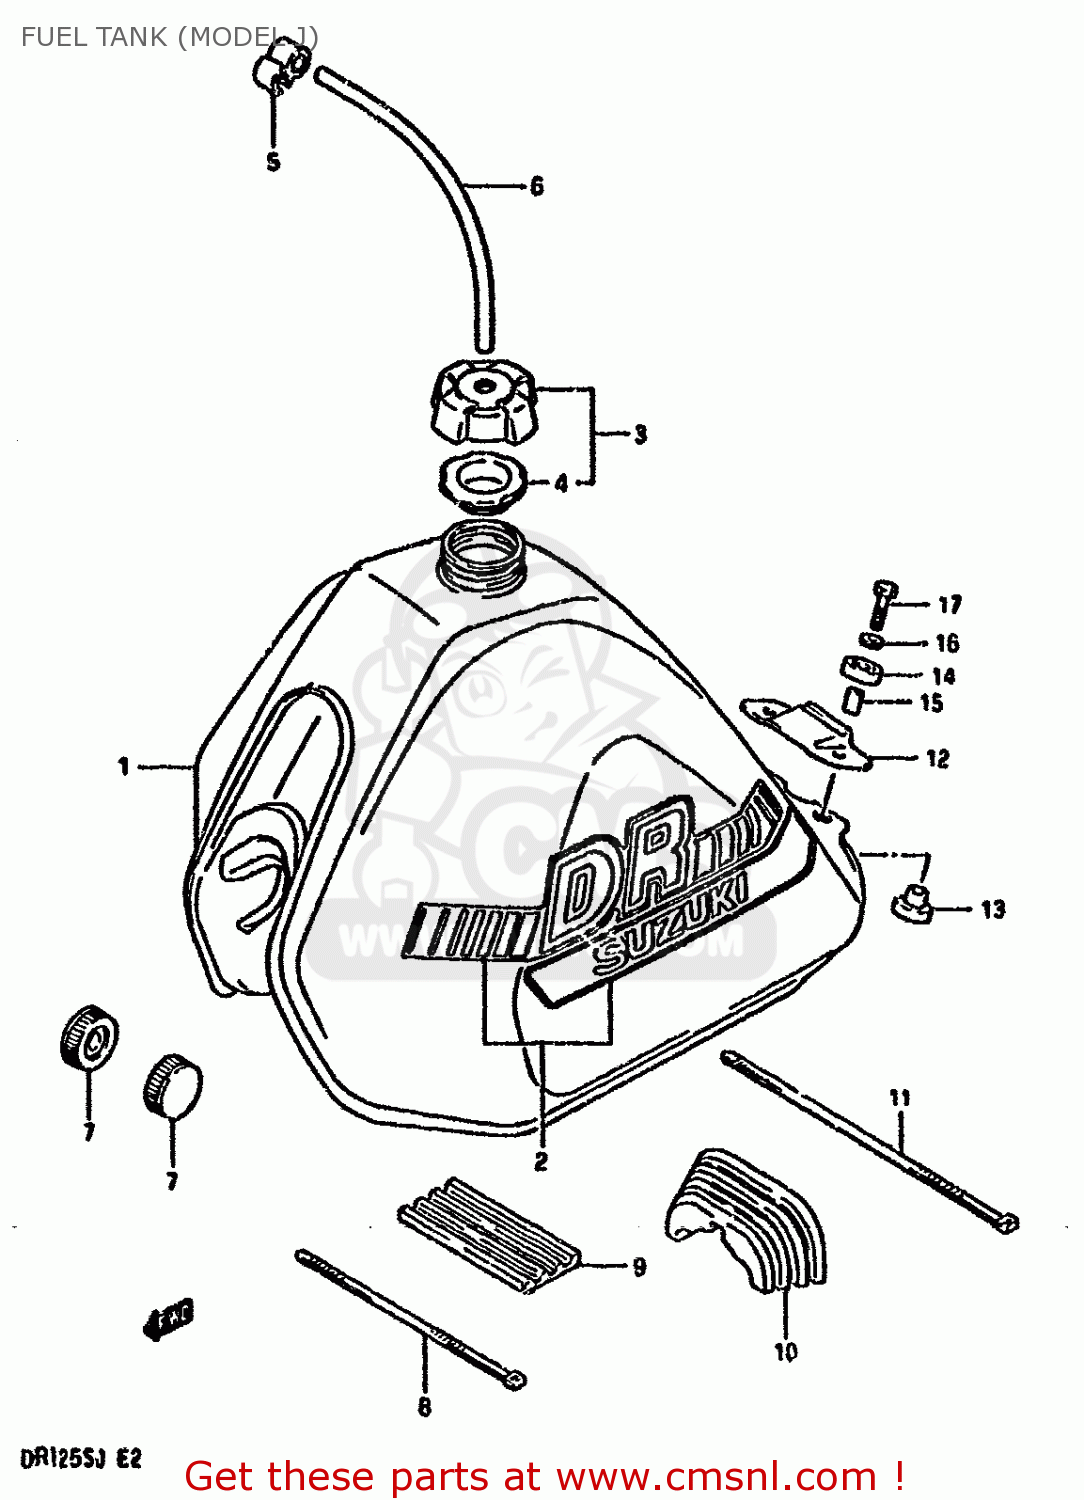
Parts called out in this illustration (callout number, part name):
1	TANK ASSY,FUEL (BLUE)
2	TAPE SET,FUEL TANK
3	CAP SET,FUEL TANK
4	GASKET (NAS)
5	CLAMP,FUEL TANK BREATHER HOSE
6	HOSE
7	CUSHION
8	CLAMP
9	CUSHION,FUEL TANK UPR FR
10	CUSHION,FUEL TANK RR
11	CLAMP(L:250)
12	PLATE,SEAT FR HOOK
13	CUSHION
14	CUSHION
15	SPACER
16	CUSHION
17	BOLT
18	SPACER
19	WASHER,LOCK
20	BOLT
21	LABEL,FUEL CAUTION
